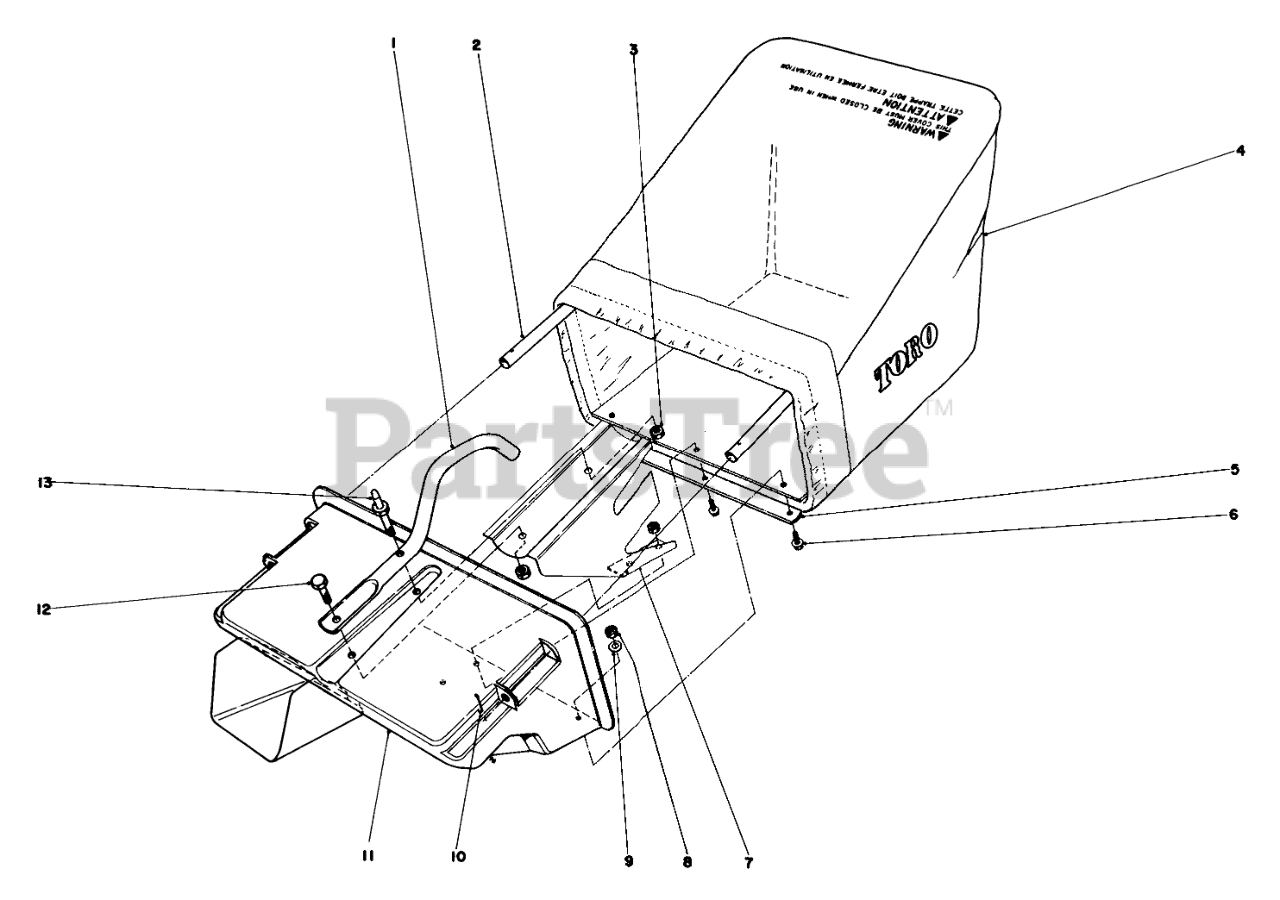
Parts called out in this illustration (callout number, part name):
1	BAG HANDLE
2	BAG FRAME
3	Nut
4	Grass Bag
5	BAG RETAINER
6	SCREW-HWH
7	BAFFLE-BAG SHELL
8	Nut
9	WASHER-FLAT
10	PIN-COTTER
11	Bag Shell
12	SCREW-HH
13	HANDLE STUD
